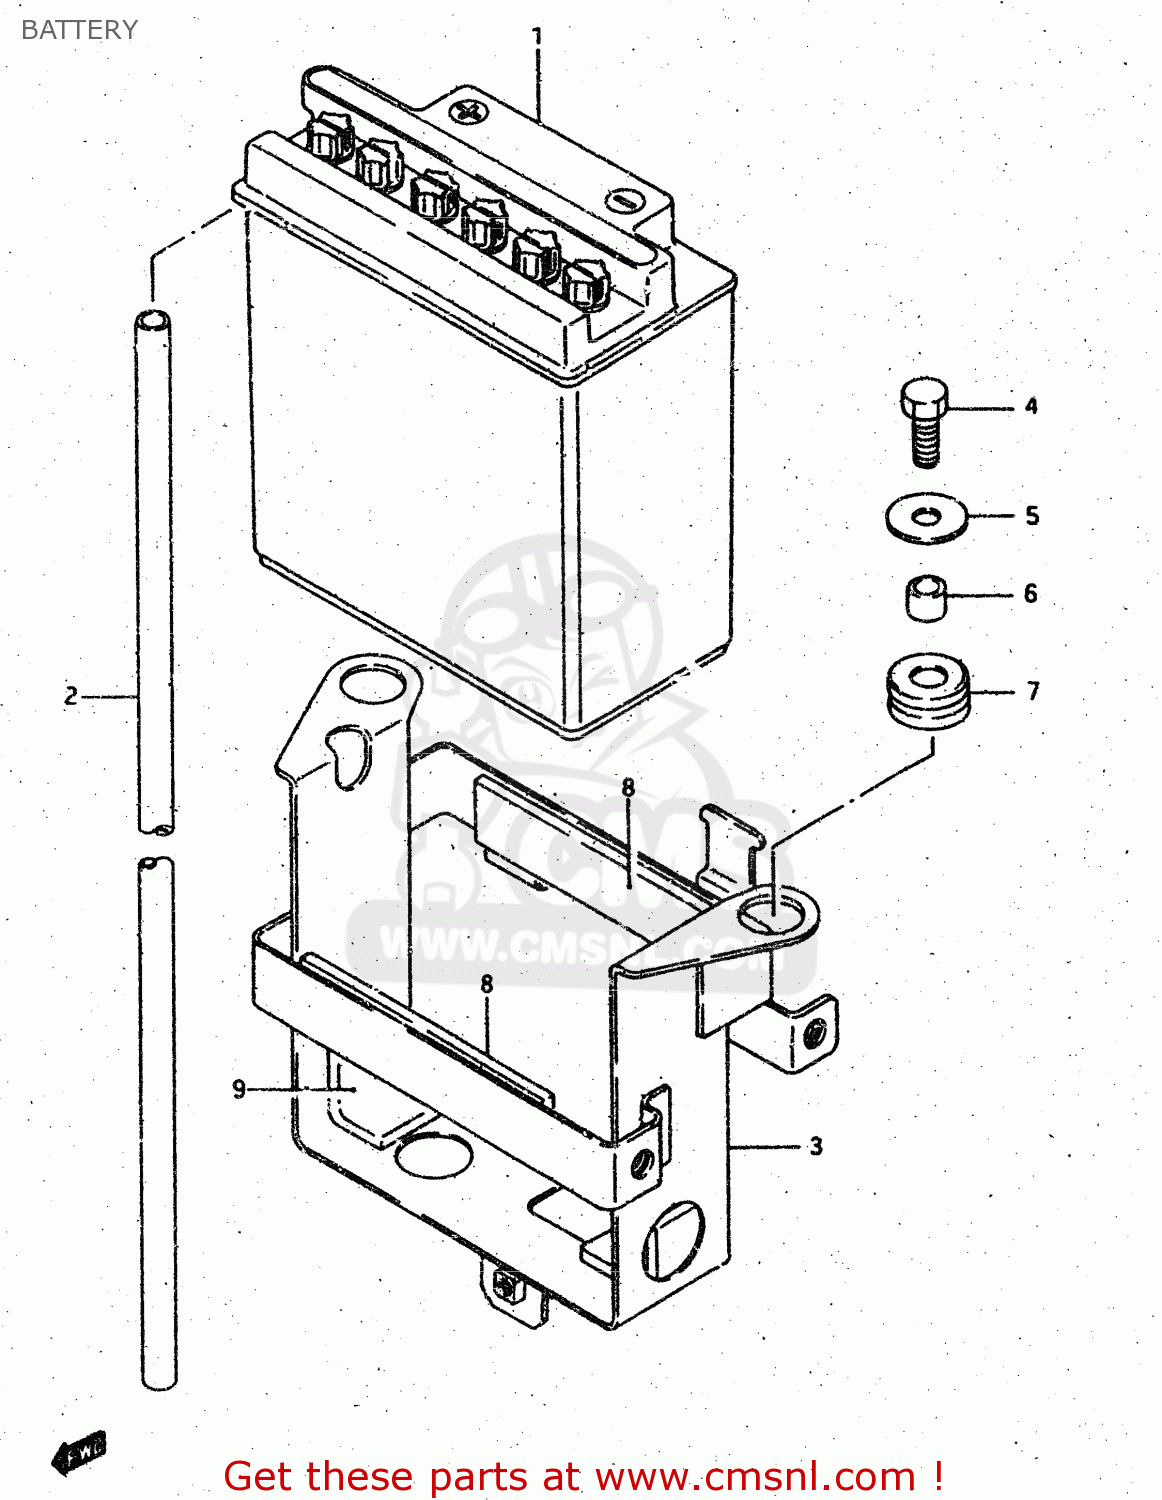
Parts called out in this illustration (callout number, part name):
1	BATTERY ASSEMBLY (12V)
2	HOSE,BATTERY EXHAUST
3	HOLDER,BATTERY
4	BOLT,M6X1X20
5	WASHER (6.5X20X1.2)
6	SPACER (6.1X9X7.5)
7	CUSHION
8	PROTECTOR,20X9
9	PROTECTOR(30X80X2)
